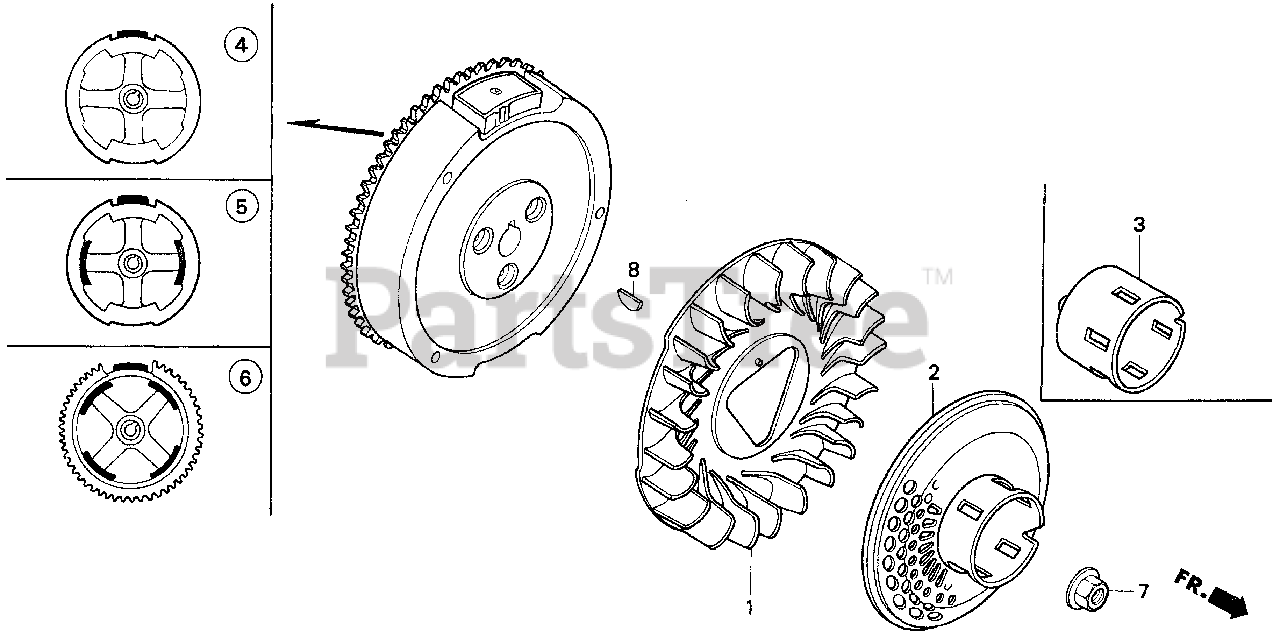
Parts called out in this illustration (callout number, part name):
1	FAN, COOLING
2	PULLEY, STARTER (SCREEN GRID)
4	FLYWHEEL
7	NUT, SPECIAL (16MM) (1)
8	KEY, SPECIAL WOODRUFF (25X18)
